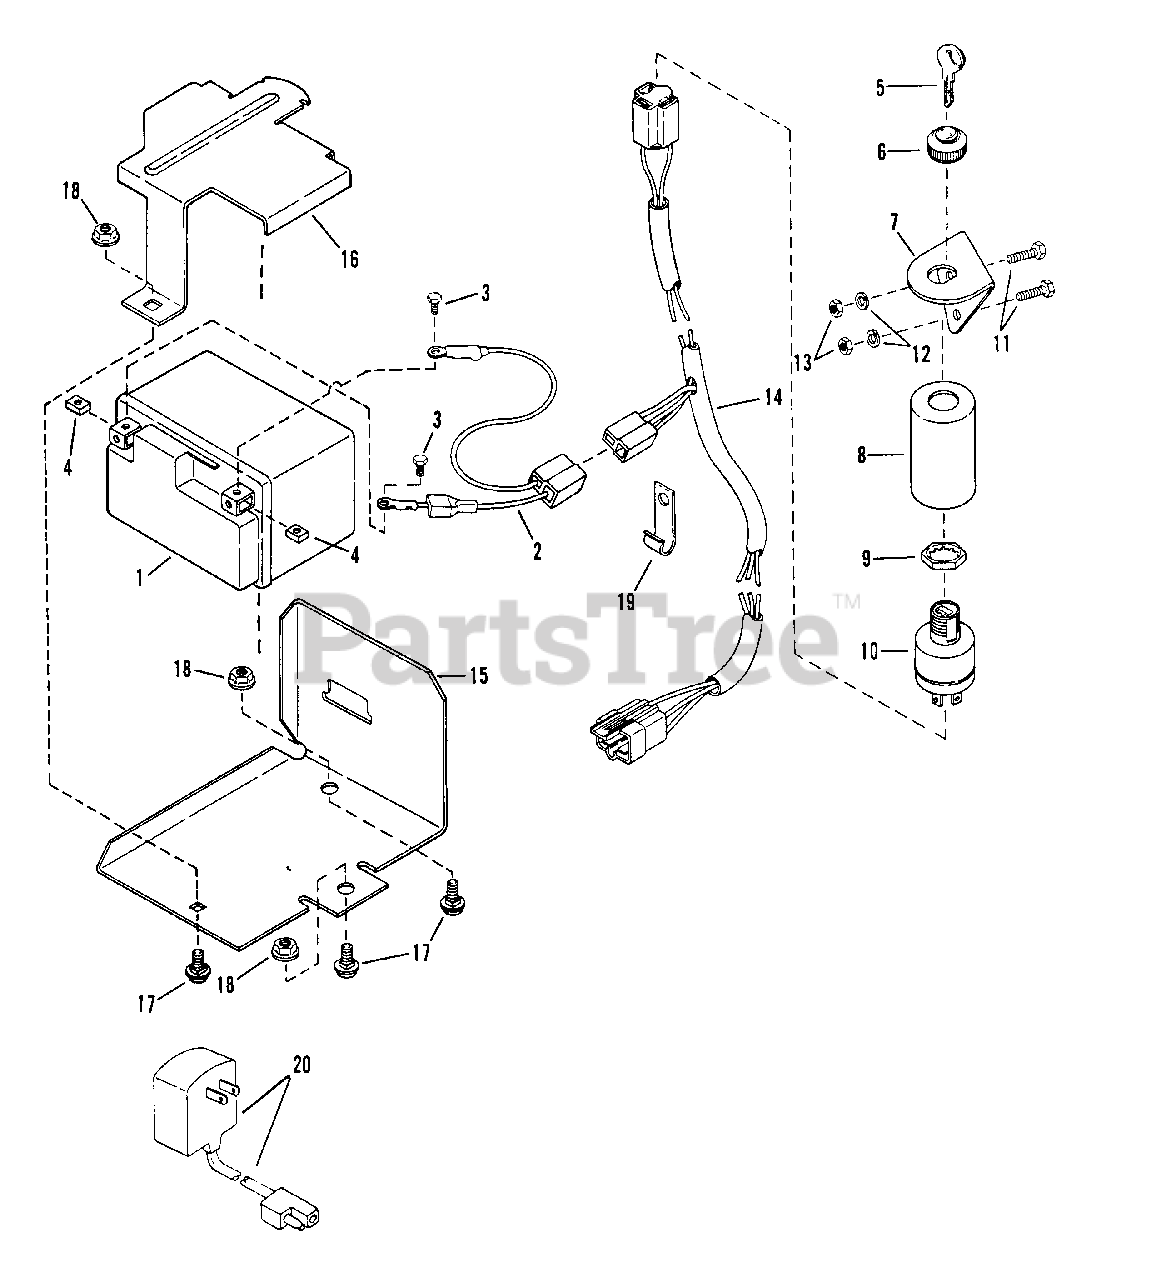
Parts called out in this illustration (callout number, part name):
1	BATTERY,12 Volt
2	HARNESS, Battery
3	SCREW, #10-24 x 1/2 Hex Head Cap
4	NUT, #10-24 Square
5	KEY, (Set of 2)
6	ASSEMBLY, Seal & Face Nut
7	BRACKET, Ignition Switch
8	COVER, Switch
9	NUT, 3/4-20 Lock
10	SWITCH, Ignition
11	SCREW, 1/4-28 x 1 3/8" Hex Head Cap
12	WASHER, 1/4 Internal Tooth Lock
13	NUT, 1/4-28 Hex
14	HARNESS, Wiring
15	BRACKET, Battery
16	COVER, Battery
17	BOLT, 5/16-18 x 1/2" Carriage
18	NUT, 5/16-18 Hex Flange Lock
19	CLIP, Wiring
20	CHARGER, Battery (60 Hertz)
